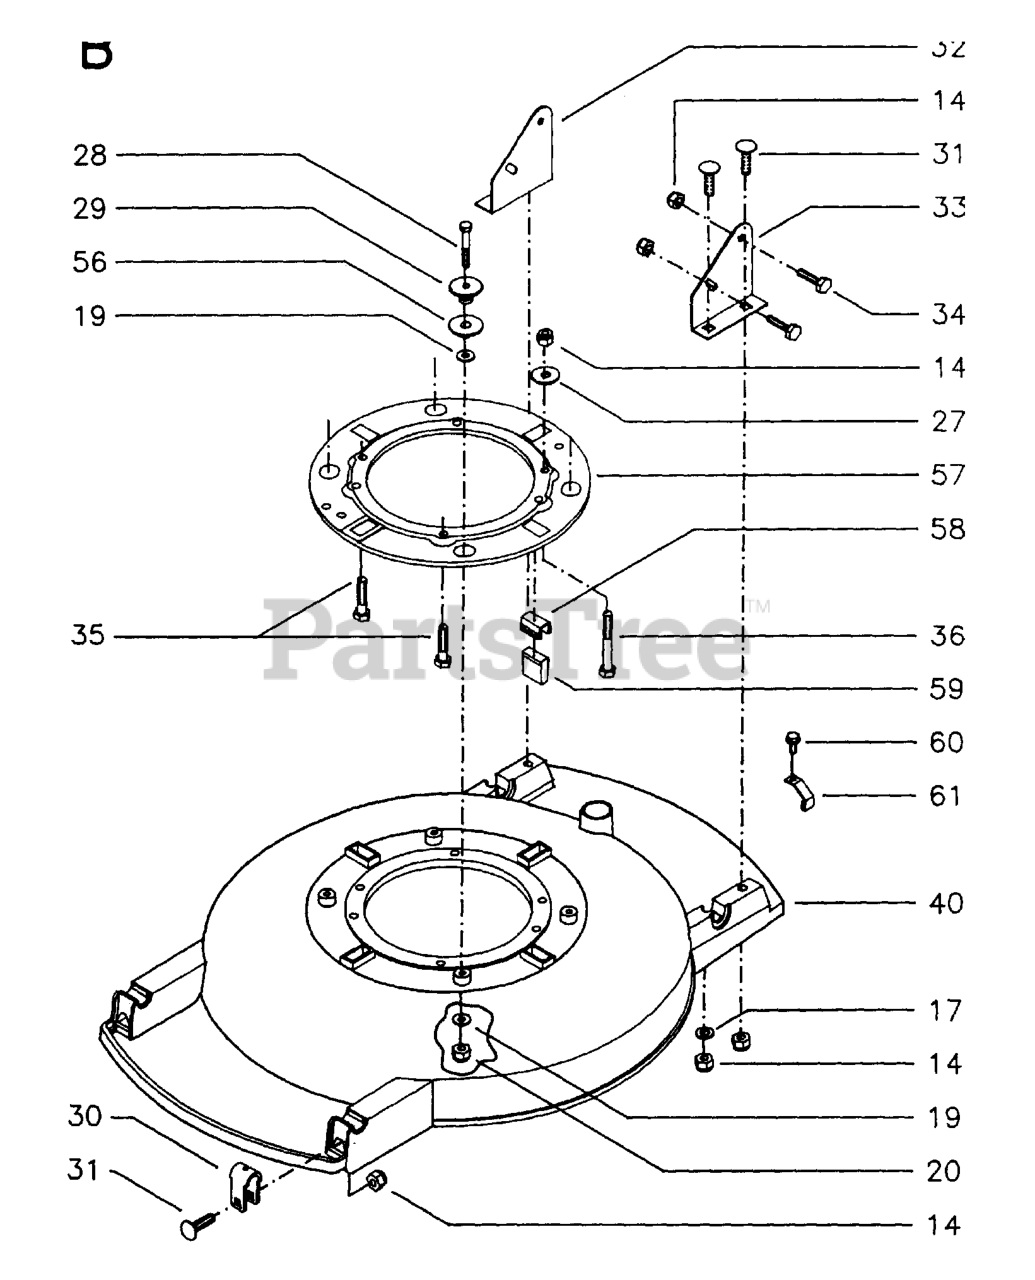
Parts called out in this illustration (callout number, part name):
14	LOCKNUT M8
17	WASHER - 15X7.3X1.6
20	LOCKNUT M6
30	BEARING HOLDER
32	HANDLE BRACKET
33	HANDLE BRACKET
34	BOLT - M8X16
56	RUBBER PIECE
59	DAMPER
